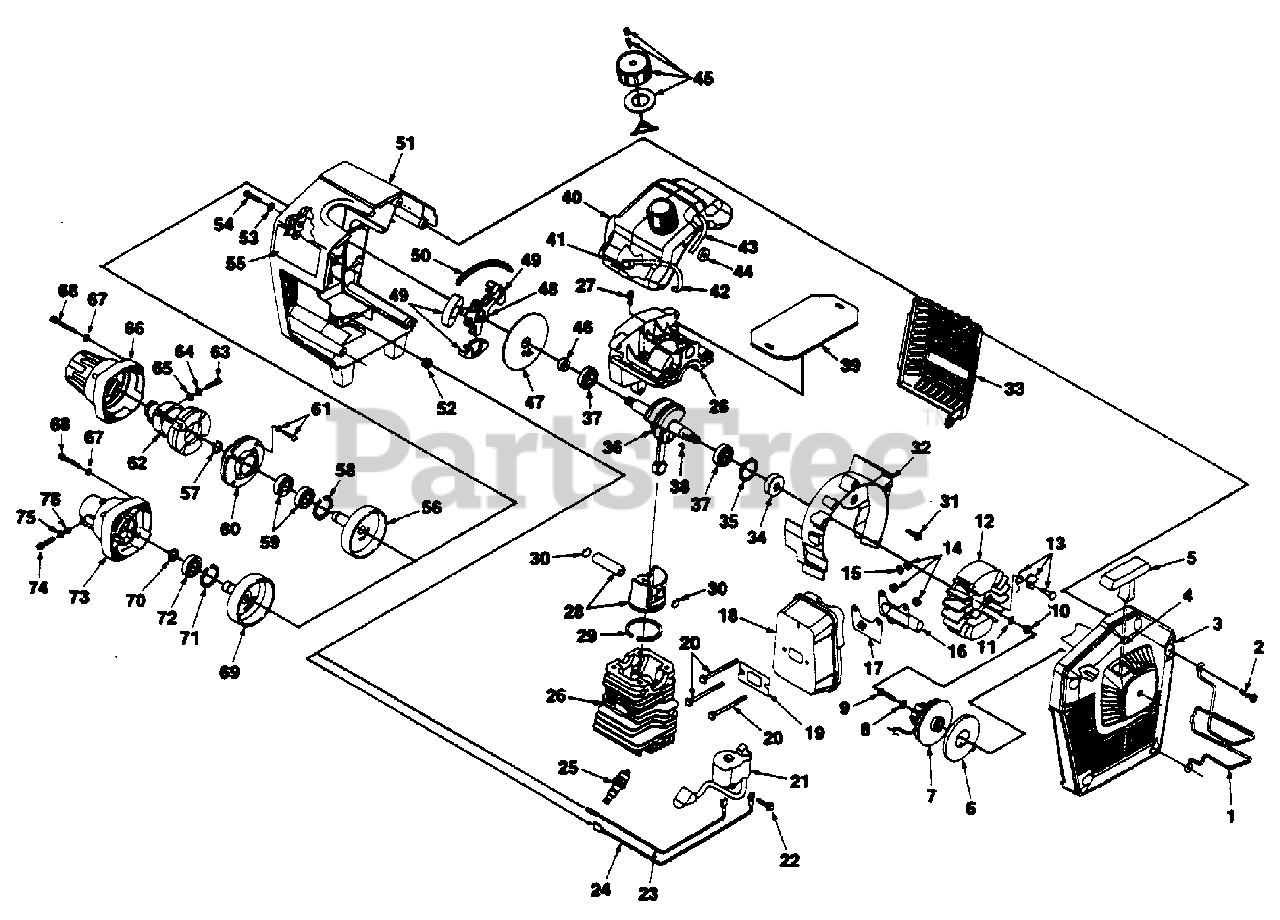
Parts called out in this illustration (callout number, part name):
1	GUARD- Wire
2	SCREW- Truss hd (10-24 x 7/8")
3	HOUSING- Starter
4	ROPE- Starter
5	GRIP- Starter
6	SPRING & CONTAINER
7	PULLEY- Starter
8	WASHER (#10)
9	SCREW (#10)
10	NUT-Rotor (3/8-24)
11	WASHER- Lock (3/8")
12	ROTOR ASSEMBLY
13	STARTER PAWL KIT
14	NUT- (10-32)
15	WASHER (#10)
16	COVER- Exhaust
17	SCREEN- Spark arrestor
18	MUFFLER
19	GASKET- Muffler
20	SCREW- (10-32 x 2 1/2")
21	MODULE- Ignition (Phelon)
22	SCREW (10-24)
23	WIRE- Ignition
24	WIRE- Ignition ground
25	SPARK PLUG (CJ6Y)
26	CYLINDER 8 CRANKCASE
27	SCREW- Hex hd. (12-24 x 7/8")
29	RING- Piston
30	RING- Piston pin ret.
31	SCREW-Truss hd. (10-24 x 3/4")
32	SCROLL- Fan
33	SHIELD- Muffler
34	SEAL- Shaft
35	RING- Retaining
36	CRANKSHAFT
37	BEARING- Ball
38	KEY- Woodruff
40	TANK- Fuel
41	FILTER- Fuel
42	TUBING- Rubber (8")
43	TUBING- Rubber (9 1/4")
44	SPACER- Fuel tank
45	FUEL CAP ASSEMBLY FILTER VALVE- Duck bill GASKET- Fuel cap
46	SEAL-Crankshaft
47	PLUG- Crankcase
48	CLUTCH- Spider
49	SHOE- Clutch
50	SPRING- Clutch
51	SHROUD
52	GROMMET
53	WASHER (#12)
54	SCREW (12-24 x 3/4")
55	DECAL-Conformity (Int'l Only)
56	DRUM- Clutch (HBC-40)
58	RlNG-Snap (HBC-40)
59	BEARING- Ball (HBC-40)
60	COVER- Clutch (HBC 40)
61	SCREW- (M5 x 22) (HBC-40)
62	INSERT RING ASSEMBLY (HBC-40)
63	SCREW- Socket (M5 x 25) (HBC-40)
64	WASHER- Spring (HBC-40)
65	WASHER- Plain (HBC-40)
66	CLUTCH CASE (HBC-40)
67	WASHER
68	SCREW (12-24 x 1 1/2")
69	DRUM- Clutch (HBC-38)
71	RING- Snap (HBC-38)
72	BEARING- Ball (HBC-38)
73	CASE- Clutch (HBC-38)
74	SCREW (HBC-38)
75	WASHER- Plain (HBC-38)
76	WASHER- Spring (HBC-38)
